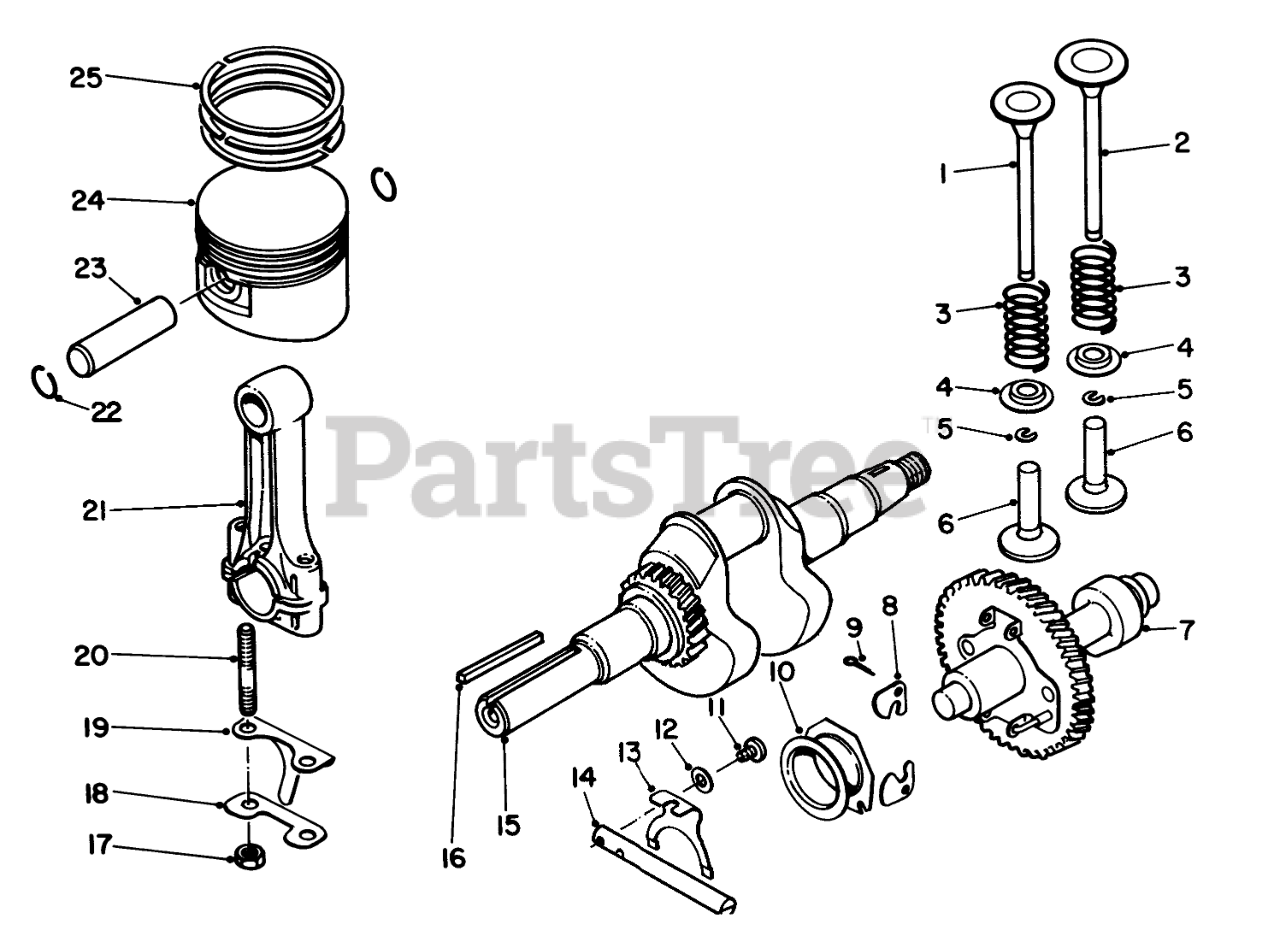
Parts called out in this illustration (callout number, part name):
1	Valve-Exhaust
2	Valve-Intake
3	Spring-Valve
4	Retainer
5	Cotter
6	Tappet (L:36.39)
7	Cam Shaft
9	Cotter Pin
10	Spacer
11	SCREW
12	Washer
13	Plate-Shift
14	Shaft-Throttle Return
18	LOCK PLATE
19	PLATE
20	Stud Bolt
21	Connecting Rod Assembly (Std.) (Incl. Ref. #17-20)
22	CIRCLIP
23	PISTON PIN
24	Piston Std.
25	Ring Set-Piston Std.
